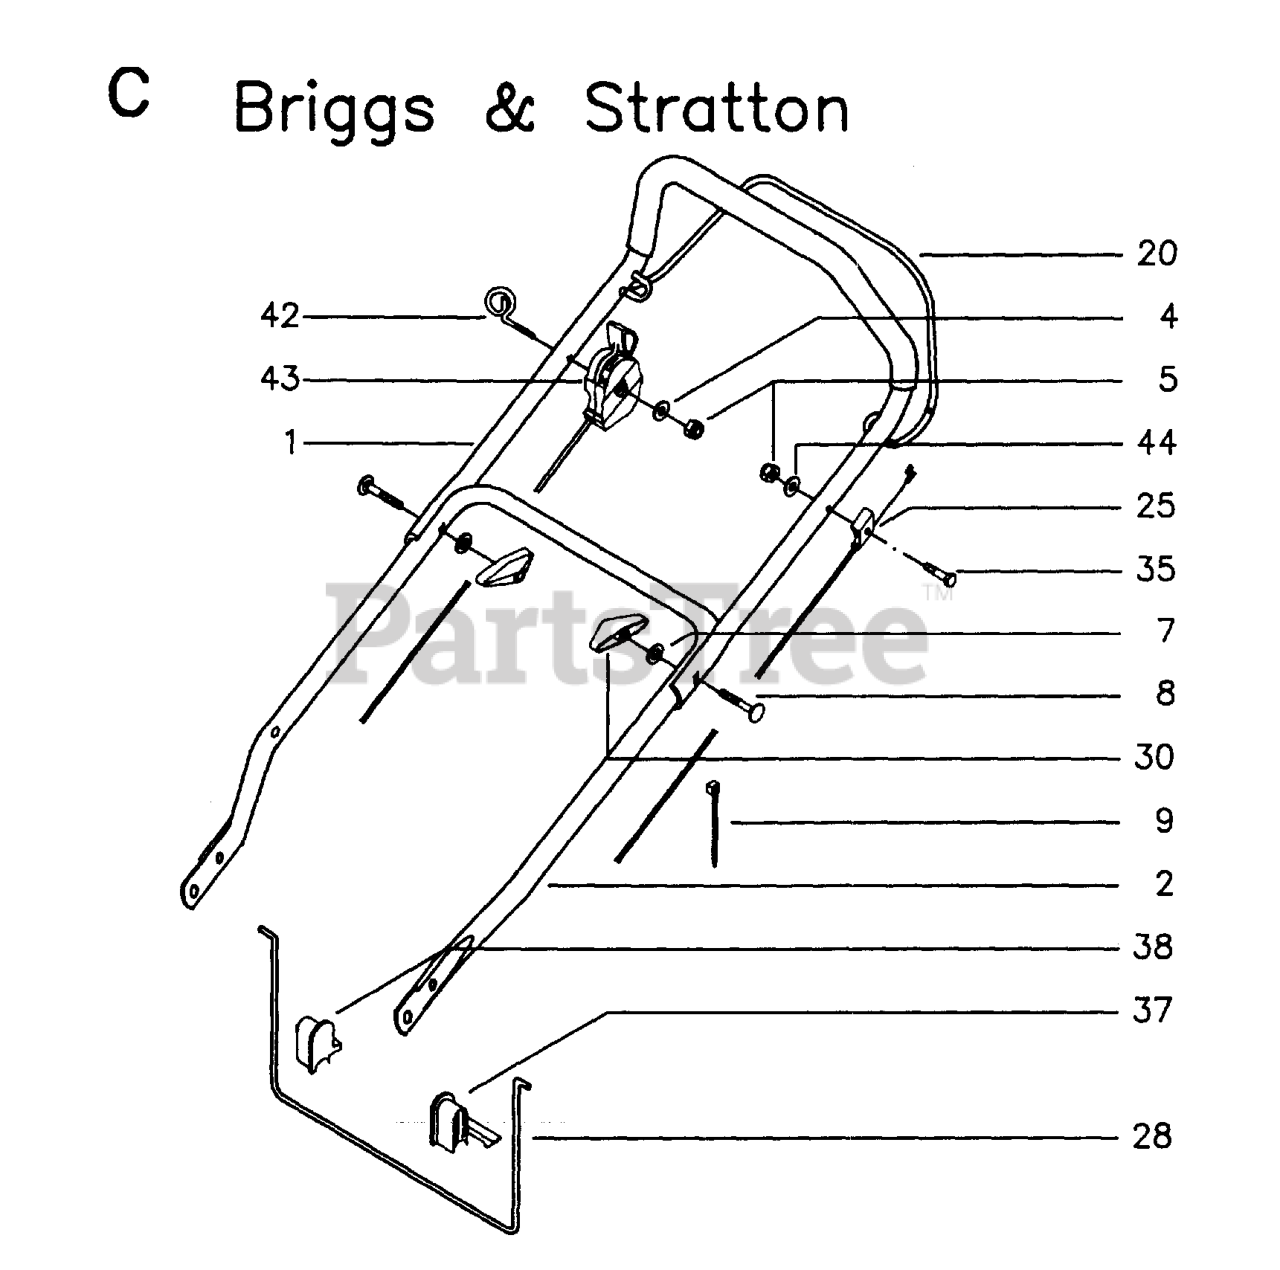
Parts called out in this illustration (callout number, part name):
2	LOWER HANDLE
5	LOCKNUT M6
25	WIRE MASTER 46
28	HANDLE BAR
30	WINGNUT
35	BOLT FLANGE
43	REPL BY 517 81 00-00
